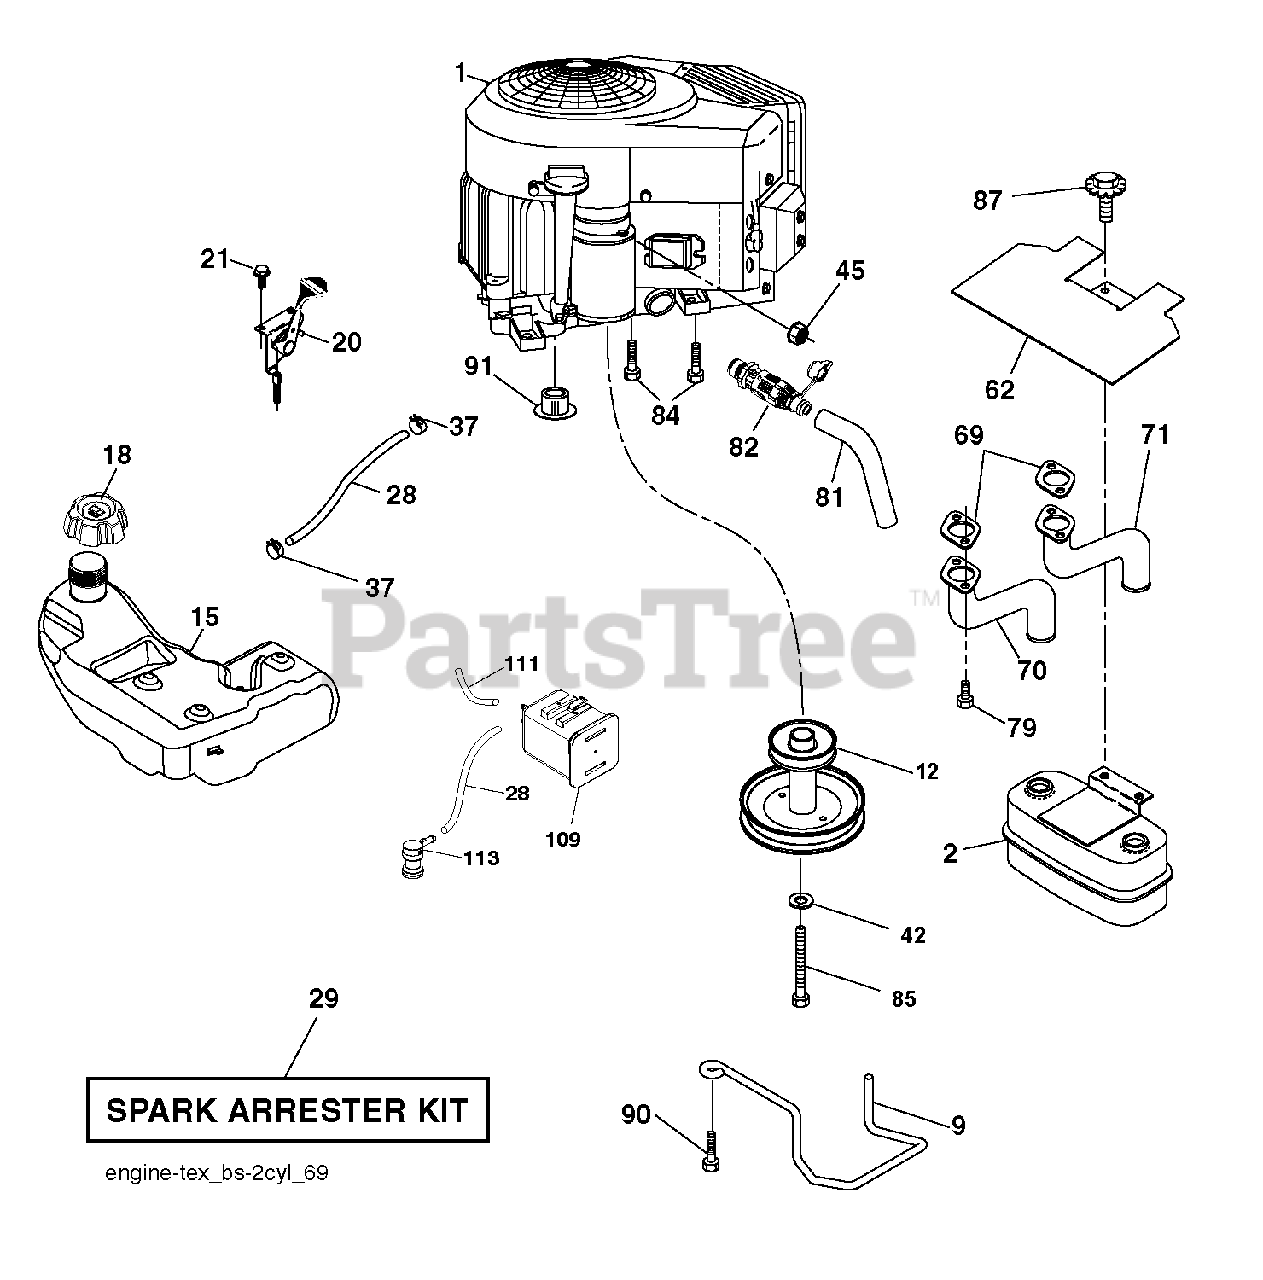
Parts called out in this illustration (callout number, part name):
1	Poulan TBD
2	MUFFLER.TWIN.CYL.LOW.TONE
9	KEEPER.BELT.ENGINE.4.2
12	PULLY ENGINE
15	TANK.ASM.FUEL.3GA.CARB
18	CAP ASM.FL.RTCHT.3"GRY.E10
20	CONTROL.TH/CK.COBRA.B&S.TWN.
21	SCREW.#10 X 0.750.BOS (2 2)
28	LINE.FUEL.64"REAR.EMIS
29	KIT.SPARK ARRESTOR(392390 B&S)
37	HOSE CLAMP
42	LOCKWASHER
45	NUT
62	SHIELD.HEAT.MUFFLER
69	GASKET.MUFFLER
70	RP.EXHAUST.TUBE.LH.BS/TWIN
71	RP.EXHAUST.TUBE.RH.BS/TWIN
79	SCREW.SOCKET.HEAD.5/16-18
81	TUBE, DRAIN OIL ASM.
82	VALUE.OIL.DRAIN
84	SCREW.3/8-16
85	BOLT HEX 7/16-20X4-1/4"
87	BOLT, 5/16-18 X 1 3/4
90	SCREW 3/8-16X1
91	BUSHING.1.375OD
109	CANNISTER, CARBON
110	VALVE.ASM.ANTI-SLOSH
111	PURGE.LINE.36"REAR.CALIFORNIA
113	VALVE.SLANT.CARTRDG.90 DEG.TEX
